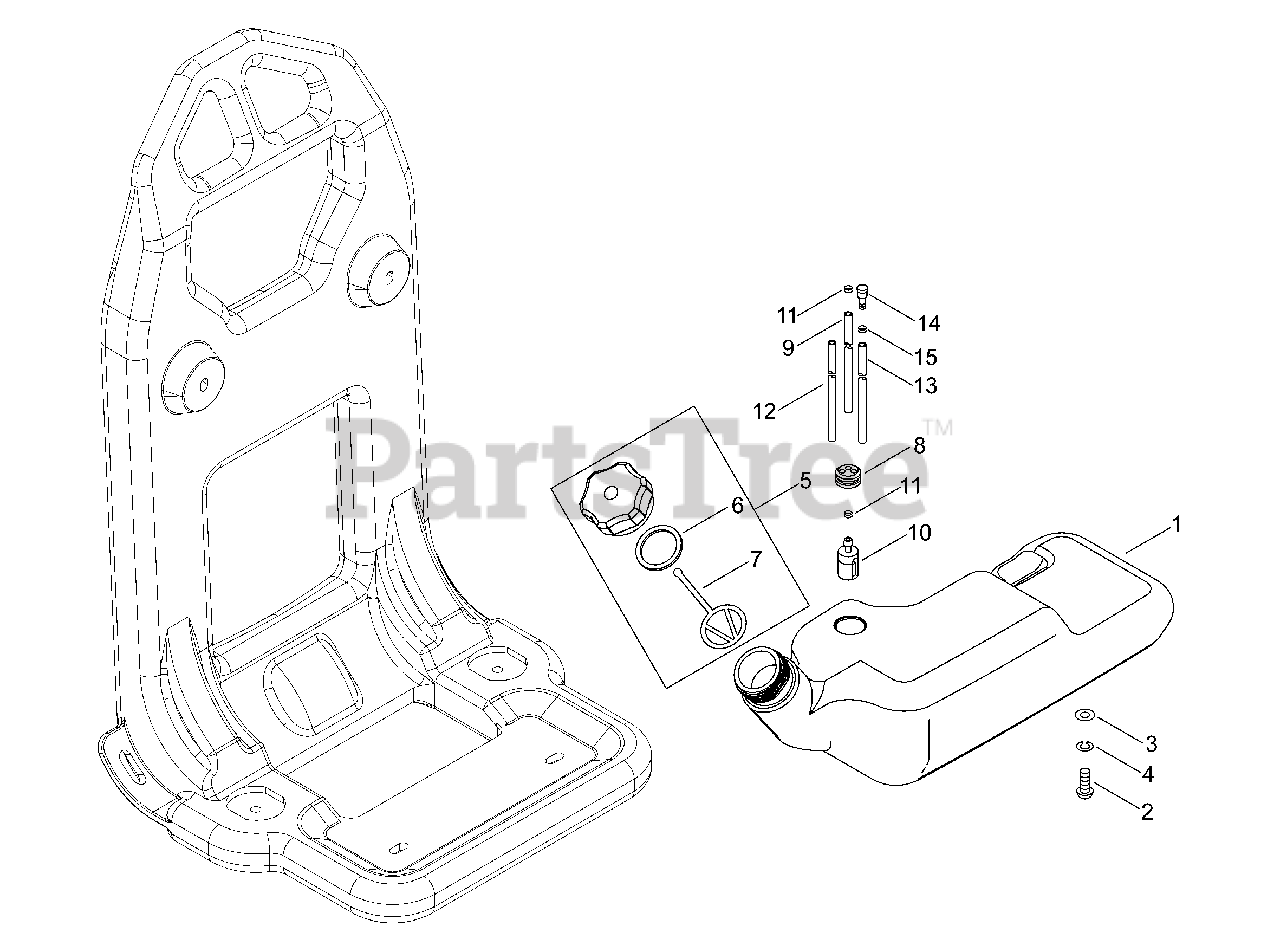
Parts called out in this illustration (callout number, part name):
1	TANK, FUEL
2	SCREW 6×14
3	WASHER 6.5×18×1.6
4	WASHER, SPRING 6
5	CAP ASSY, FUEL
6	GASKET, FUEL CAP
7	CONNECTOR, CAP L= 100mm
8	GROMMET, FUEL
9	PIPE, FUEL 3×6×280mm
10	FILTER, FUEL
11	CLIP 6.5MM
12	PIPE, FUEL RETURN 3×6×145
13	PIPE, FUEL 3×6×110
14	VENT ASSY
15	CLIP, TUBE
